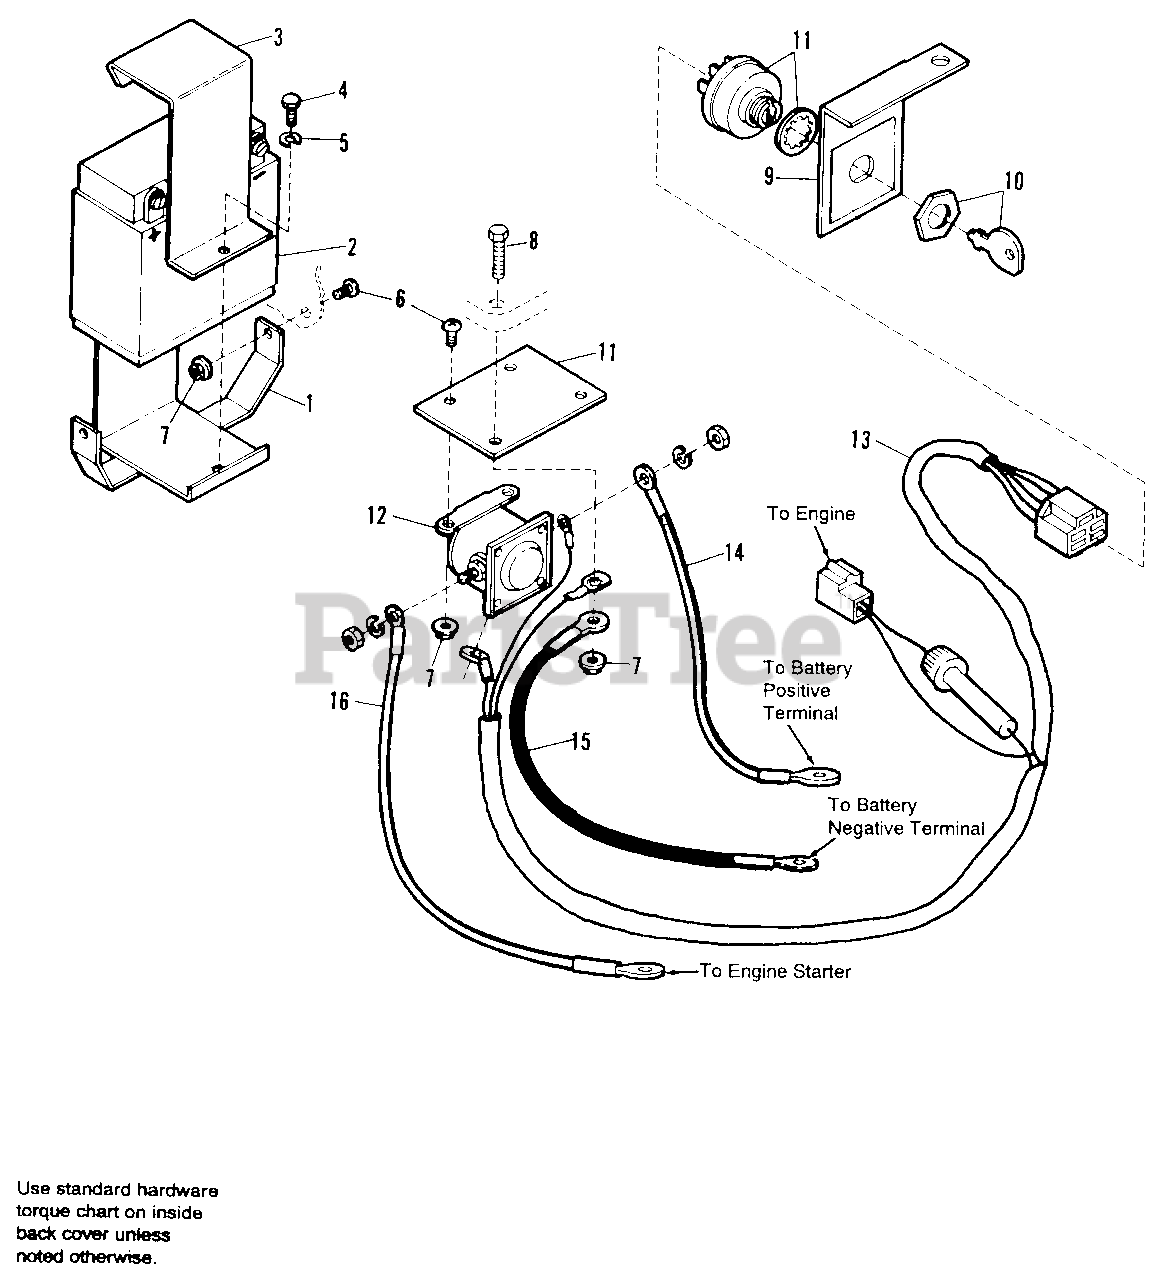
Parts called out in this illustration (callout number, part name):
1	RACK, Battery
2	Battery , 12 Volt
3	TIE DOWN, Battery
4	CAPSCREW, Hex, 1/4-20 x 1
5	LOCKWASHER, 1/4
6	SCREW, Round.Hd., Phillips, 1/4-20 x 1/2
7	NUT, Flange, Whiz Lock, 1/4-20
8	CAPSCREW, Hex Hd., 1/4-20 x 1-1/2
9	Bracket, Switch
10	SWITCH
11	BRACKET, Solenoid
13	WIRE HARNESS ASSY.
14	CABLE, Positive-to-Solenoid, Red, "7"
15	CABLE, Negative-to-Ground, Black, 9"
16	CABLE, Solenoid-to-Starter, Red, 14"
